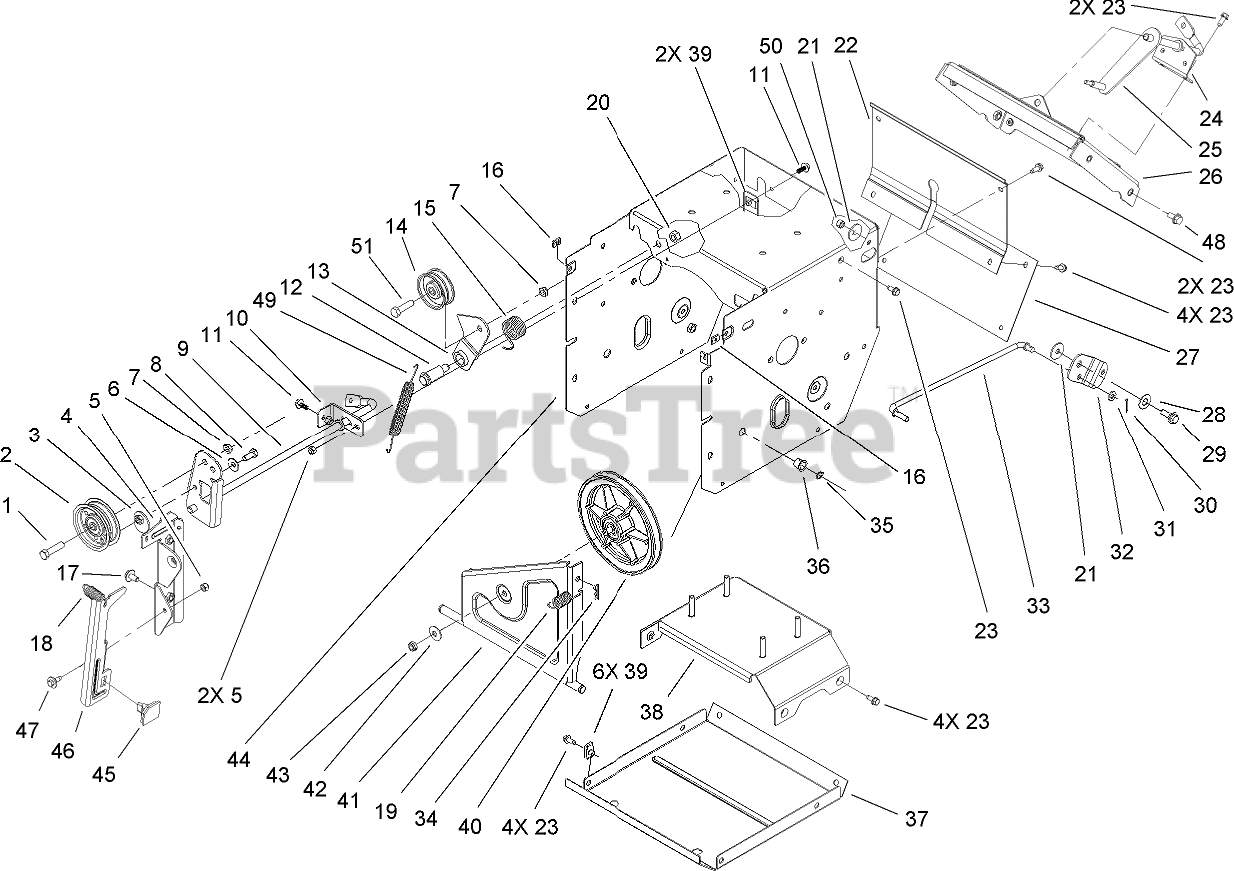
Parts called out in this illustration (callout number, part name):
1	SCREW-HH
2	PULLEY-IDLER
4	BRACKET-IDLER, IMPELLER
5	NUT-LOCK, NI
6	WASHER-BELLEVILLE
7	NUT-LOCK, NI
8	SCREW-HH
9	IMPELLER CLUTCH ASM
10	BRACKET-REAR, CLUTCH
11	SCREW-HHF
12	BOLT-SHOULDER
13	ARM-IDLER, TRACTION
14	PULLEY-IDLER
15	SPRING-TORSION
16	NUT-SPEED, U-TYPE
17	SCREW-HHF
18	SPRING-EXTENSION
19	SPRING-EXTENSION
20	NUT-LOCK, NI
21	WASHER-PIVOT
22	COVER-UPPER
23	SCREW-HWH
24	BRACKET-ROD, SHIFT
25	LEVER-CONTROL, TRACTION
26	SHIFT PLATE ASM
27	COVER-LOWER
28	WASHER
29	SCREW-SHOULDER
30	PIN-COTTER
31	WASHER-PLAIN
32	BELLCRANK-DRIVE
33	LINK-CONTROL, SPEED
34	PIN-COTTER
35	RING-RETAINING
36	BUSHING-NYLINER
37	PAN-BOTTOM
38	BRACE FRAME ASM
40	PULLEY-TRACTION
41	BRACKET-WHEEL, FRICTION
42	WASHER-BELLEVILLE
43	NUT-HEX
44	TRACTION FRAME ASM
45	PAD-BRAKE
46	ARM-BRAKE
47	SCREW-SHOULDER
48	SCREW-HWHTF
49	SPRING-EXTENSION
50	NUT-LOCK, NI
51	SCREW-HH
